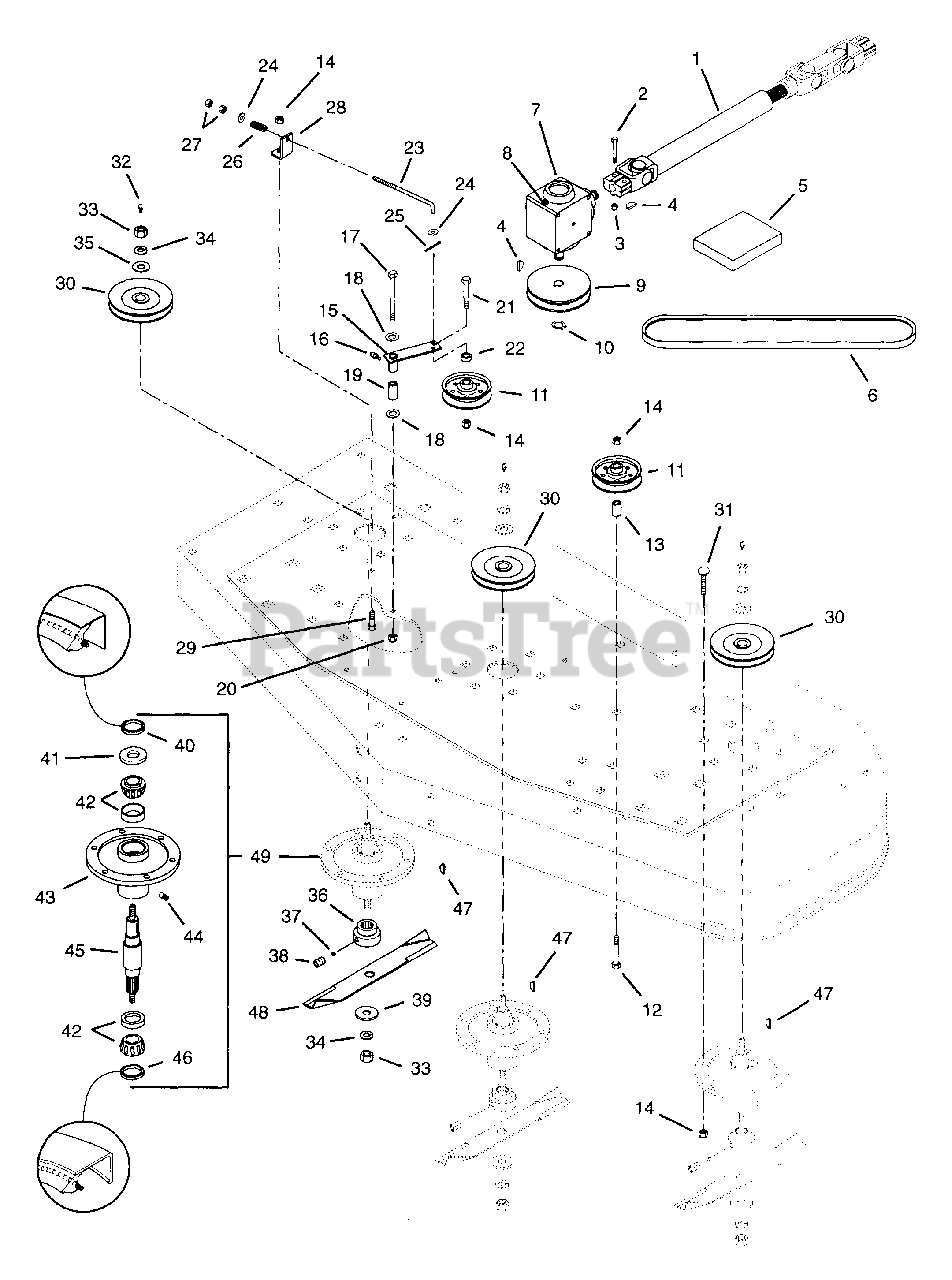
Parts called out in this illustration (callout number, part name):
1	C.V. Universal Joint - 60" Deck (004,300)
1	C.V. Universal Joint - 72" Deck (005,006,301,302)
2	Bolt-Hex .31-18 x 1.75 Grade 5
3	Nut-Locking-Nylon .312-18 Grade 2
4	Key, Woodruff .25 x .875
5	Kit, Repair, U-Joint
6	V-Belt B-Section 82.375 x .672 (004,300)
6	V-Belt A-Section 94.8 x .656 (005,006,301,302)
7	Gearbox, Right Angle 1:1
8	Plug, 1/8 Vent
9	Sheave, Gear Box
10	Ring-Retaining-External .821 x .078
11	Idler-Flat-Pulley 6.75 x .510
12	Bolt-Hex .50-13 x 2.75 Grade 5 (004,005,300,301)
12	Bolt-Hex .50-13 x 2.00 Grade 5 (006,302)
13	Spacer .562 x .975 x 1.00 (004,005,300,301)
13	Spacer .516 x .875 x .300 (006,302)
14	Nut-Locking-Nylon .375-16 Grade 2
15	Weldment, Idler Pivot
16	Fitting-Lube .25-28 x .256
17	Bolt-Hex .50-13 x 3.375
18	Washer-Flat-Steel .500 x 1.250 x .083
19	Spacer .505 x .855 x 2.50
20	Nut-Locking .50-13 Grade 5
21	Bolt-Hex .38 x 1.75 Grade 5
22	Spacer .516 x .875 x .300
23	Rod, Idler
24	Washer-Flat-Steel .406 x .812 x .062
25	Pin-Cotter .09 x .75
26	Spring-Compression .125 x .78 x 1.00
27	Nut-Hex .375-24 Grade 2
28	Support, Spring
29	Bolt-Hex .38-16 x 1.00 Grade 5
30	Weldment, Sheave (004,300)
30	Weldment, Sheave (005,006,301,302)
31	Bolt-Round Head Square Neck .38-16 x 1.50
32	Fitting-Lube 1/8
33	Nut-Hex .625-11 Grade 2
34	Washer-Lock .625 x .156
35	Washer-Flat-Steel .687 x 1.312 x 1.50
38	Screw-Set .25-20 x .25
39	Washer
39	Washer-Flat-Steel .687 x 1.312 x 1.50
40	Seal 1.987 x 1.500 x .313
41	Washer-Flat-Steel 1.007 x 1.542 x .062
42	Assembly, Bearing Cup and Cone
43	Bearing, Housing
44	Relief Fitting
45	Shaft, Spindle
46	Seal 1.987 x 1.375 x .313
47	Key-Woodruff .25 x 1
48	Blade (004,300)
48	Blade, 72" Mower (005,006,301,302)
49	Service Kit
